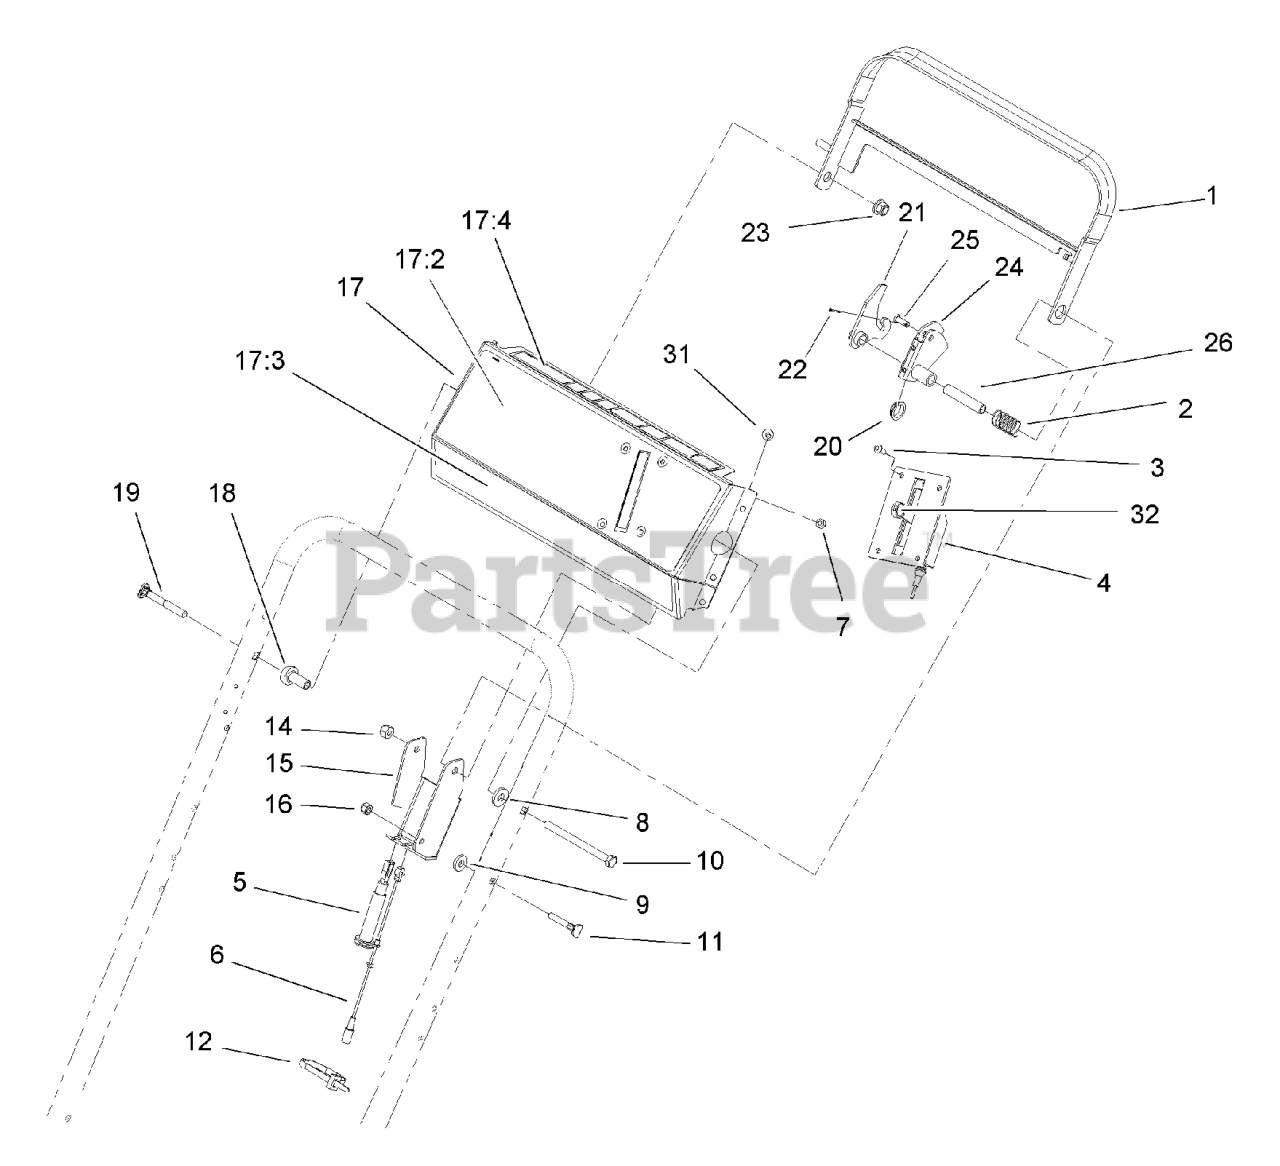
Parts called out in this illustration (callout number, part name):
1	BAR-CONTROL
2	SPRING-CONTROL
3	SCREW-PPH
5	CABLE-TRACTION
6	CABLE-CLUTCH
7	NUT-LOCK, NI
10	SCREW-HH
11	SCREW-HANDLE
12	TIE-CABLE
14	NUT-LOCK, NI
15	BRACKET-CONTROL
16	NUT-LOCK, NI
17	PANEL-CONTROLNSP
17:2	DECAL-PANEL, CONTROL
17:4	DECAL-PANEL, DANGER
18	SPACER-SUPPORT
20	BUSHING-FLANGE
21	LEVER-TRACTION
22	PIN-COTTER
23	NUT-LOCK, NI
24	LEVER-BBC
25	PIN-CABLE
26	SPACER-BRACKET, CONTROL
31	SCREW-HWHTF
